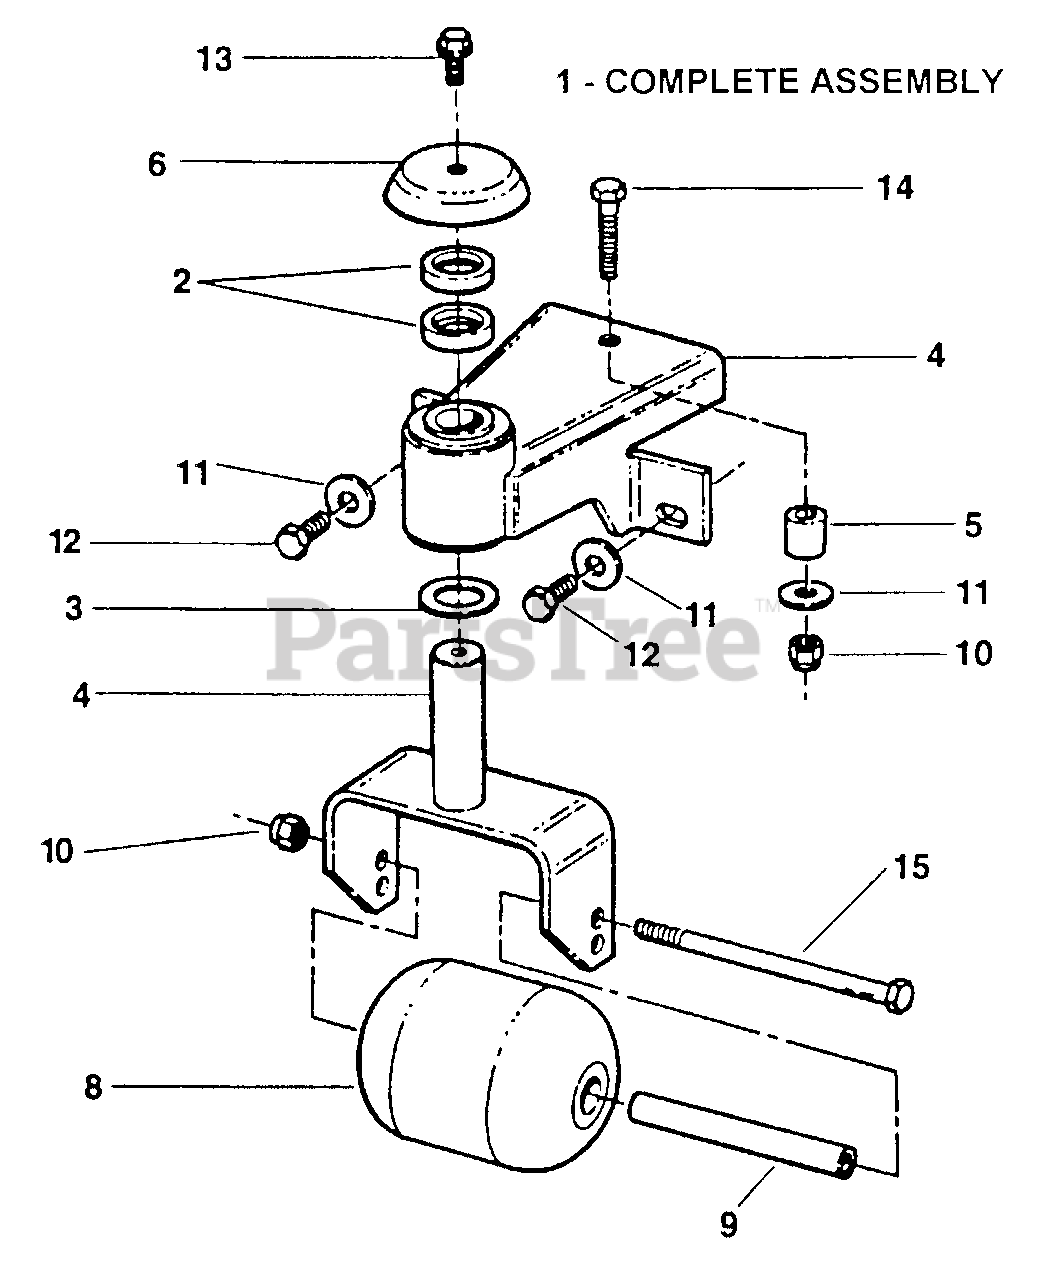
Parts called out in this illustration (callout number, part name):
1	ASSEMBLY, Roller
2	SPACER, 1" x 1 3/8 x .30" (PM)
3	BUSHING, 1" Machine
4	CASTER, Gage Wheel (Weldment)
5	SPACER, 3/8 x .75"
6	CAP, Caster Shaft
8	ROLLER, 3 3/4 x 4 13/16" Nylon
9	TUBE, Axle
10	NUT, 3/8-16 HEX NYLON LOCK
11	WASHER, 3/8" USS
12	BOLT, 3/8-16 X 1" GD5 CZ
13	SCREW, 5/16-18 x 3/4" Hex Washer Head, Self-Tapping
14	SCREW, 3/8-16 x 1 3/4" Hex Head Cap
15	BOLT, 3/8-16 X 6" GD5 CZ
